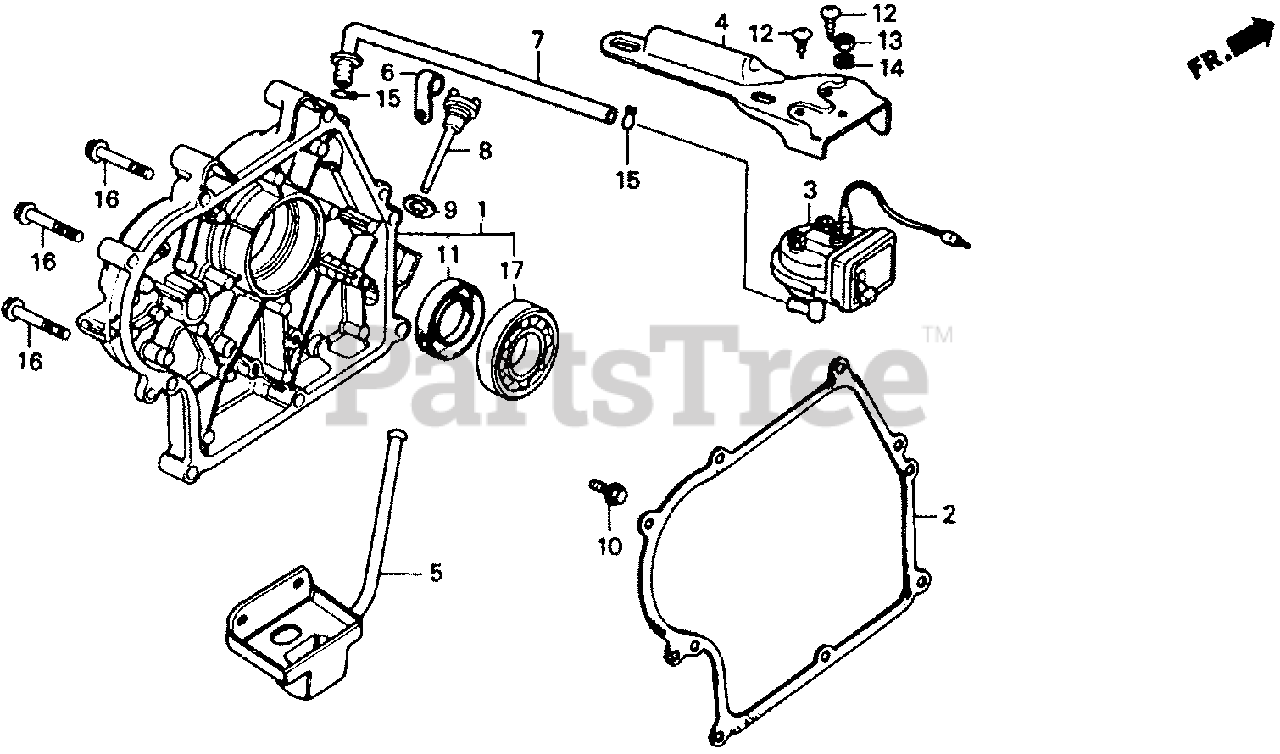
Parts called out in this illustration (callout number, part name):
1	COVER, CRANKCASE (QZ-TYPE)
2	GASKET, CASE COVER
3	SWITCH ASSY., UNIT
4	BRACKET, UNIT SWITCH
5	CUP, OIL
6	CLAMP, TUBE
7	TUBE, OIL ALERT
8	CAP, OIL FILLER
9	GASKET, OIL FILLER CAP
10	BOLT, FLANGE (6X16)
11	OIL SEAL (30X46X8)
12	SCREW, TAPPING (5X10)
13	NUT, HEX. (5MM)
14	WASHER, SPRING (5MM)
15	CLIP, TUBE (C11)
16	BOLT, FLANGE (8X40)
17	BEARING, RADIAL BALL (6206)
